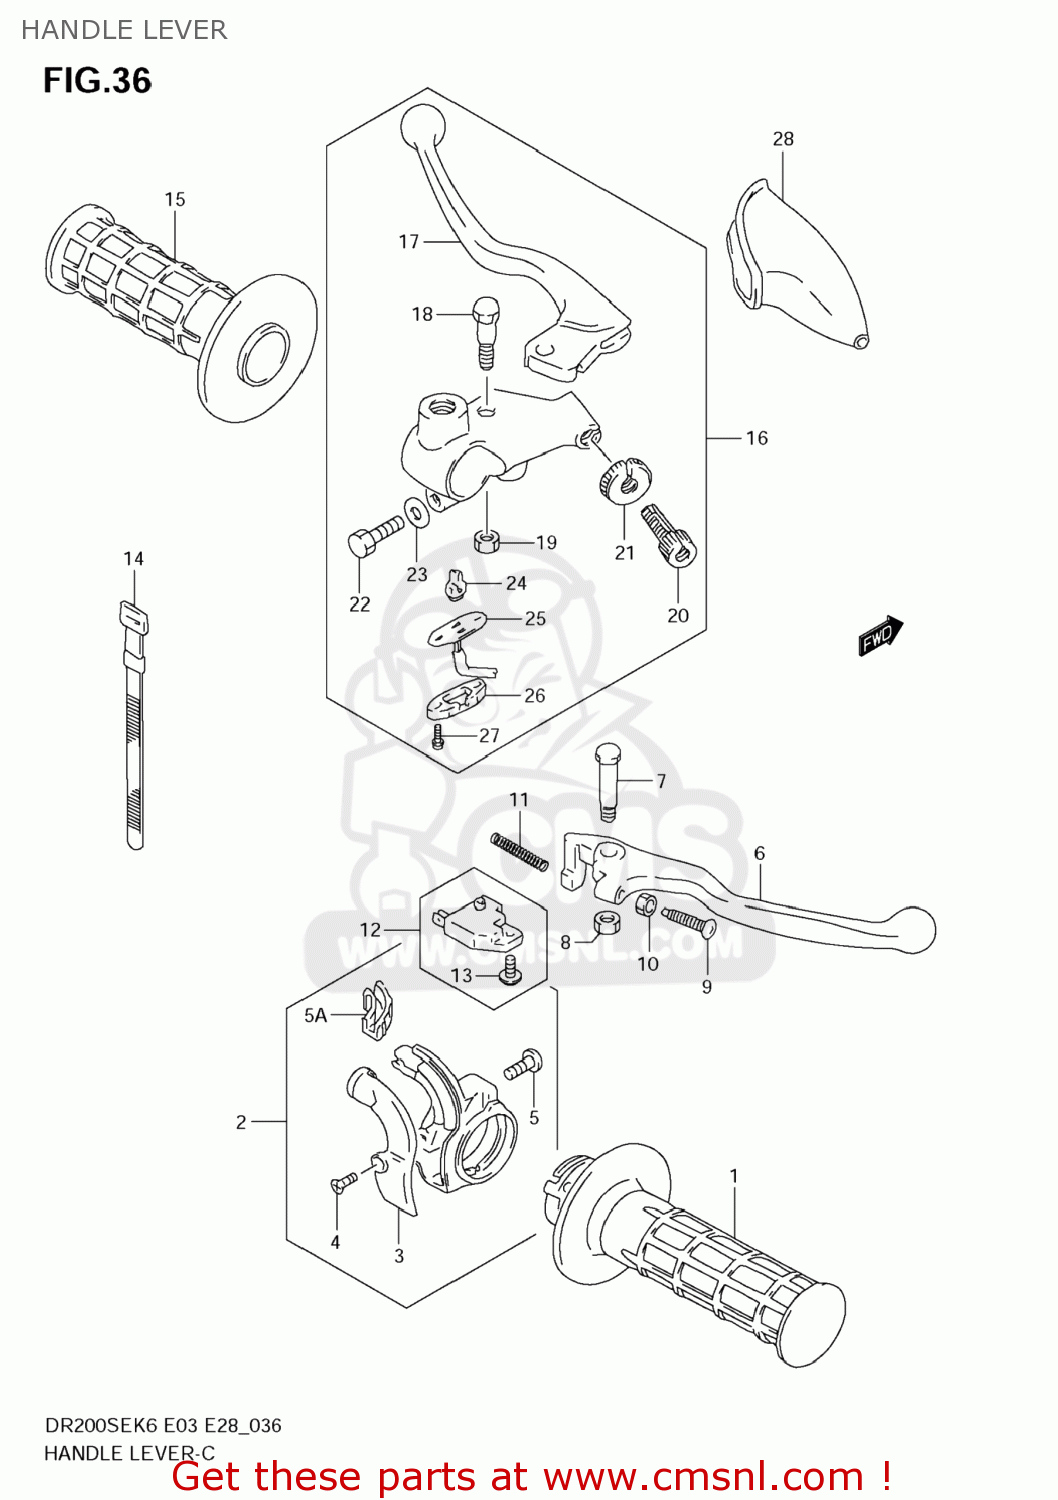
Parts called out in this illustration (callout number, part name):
1	GRIP,THROTTLE
2	CASE ASSY,THROTTLE
3	COVER,THROTTLE CASE
4	SCREW
5	SCREW
5A	GUIDE PIECE,THROTTLE
6	LEVER,BRAKE
7	BOLT,BRAKE LEVER
8	NUT
9	BOLT,ADJUST
10	NUT
11	SPRING,RETURN
12	SWITCH ASSY,ST
13	SCREW
14	CLAMP(L:120)
15	GRIP,L
16	LEVER ASSEMBLY,CLUTCH
17	LEVER,CLUTCH
18	BOLT,LEVER PIVOT
19	NUT
20	ADJUSTER,CABLE
21	NUT,LOCK
22	BOLT
23	WASHER
24	CONTACT,SWITCH
25	HARNESS ASSY,WIRE
26	COVER,FR BK TERMINAL BASE
27	SCREW
28	COVER,CLUTCH LEVER
